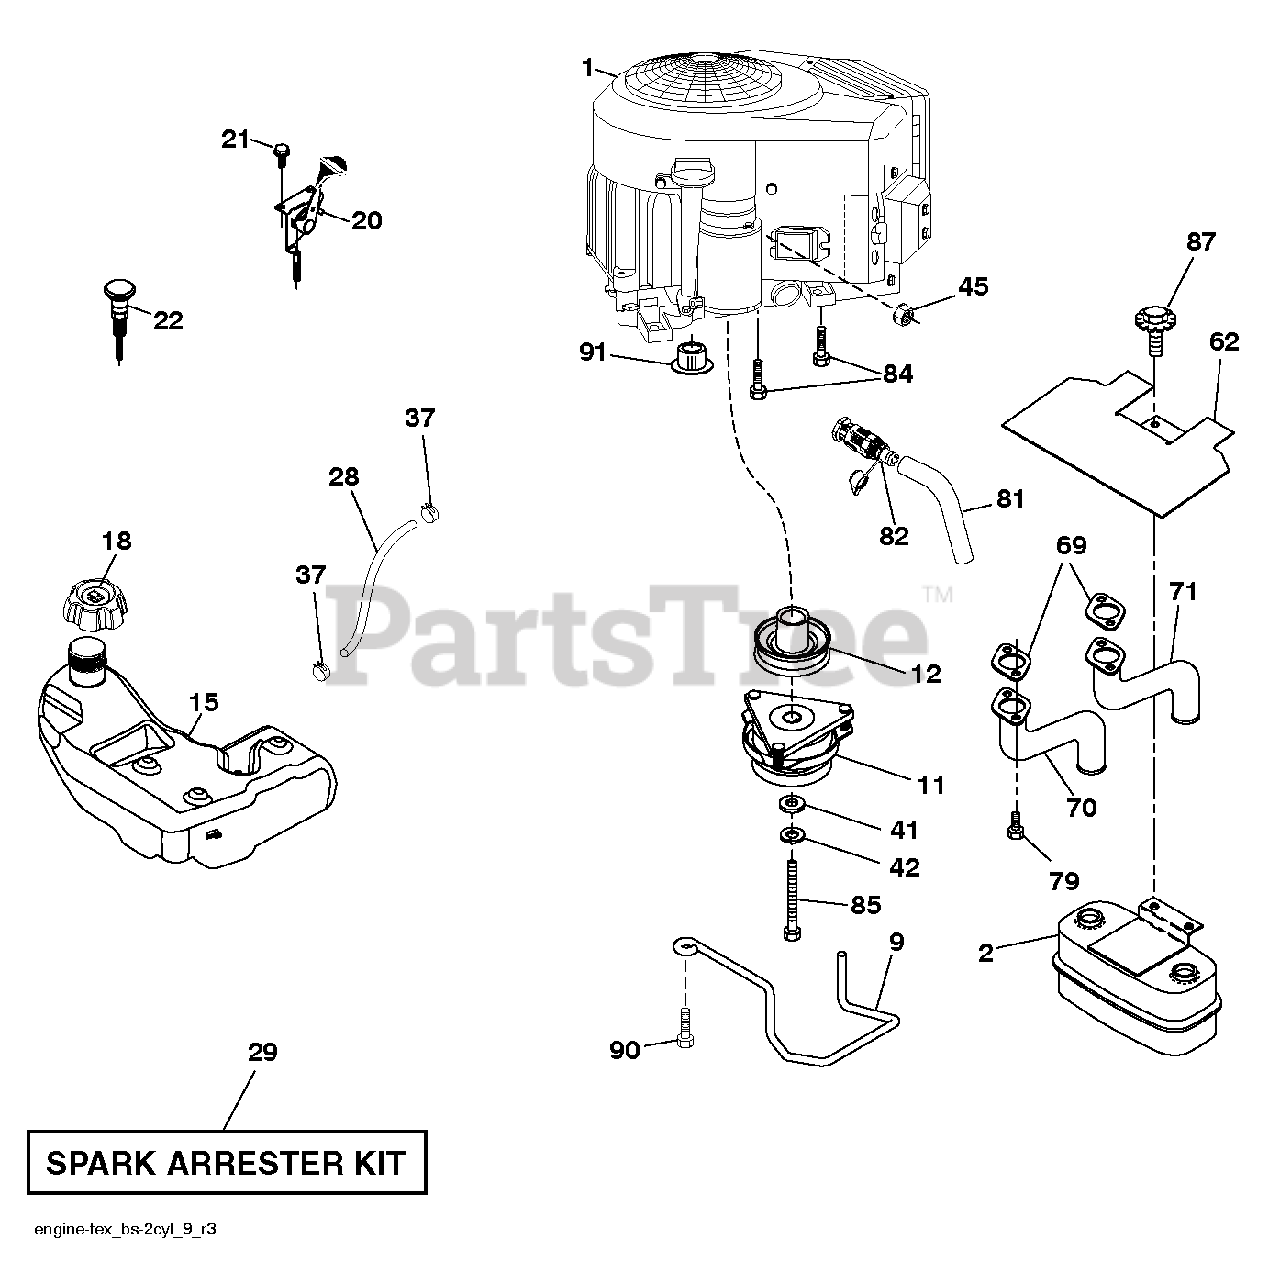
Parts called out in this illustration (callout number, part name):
2	MUFFLER.TWIN.CYL.LOW.TONE
9	KEEPER.BELT.ENGINE.4.2
11	CLUTCH.ELECTRIC.LT.48"*
12	PULLEY.ENGINE.TUFFTORQ
15	TANK.ASSY.3.GAL.EPA
18	CAP.ASM.FL.RITCH.3"E10.SYM.498
20	THROTTLE CABLE
21	SCREW.#10 X 0.750.BOS
22	CONTROL.CHOKE.ERGO.PUSH-IN.BLA
28	REPL BY 532 00 85-43
29	KIT.SPARK ARRESTOR 794945 B&S
37	HOSE CLAMP
42	LOCKWASHER
45	NUT
62	SHIELD.HEAT.MUFFLER
69	GASKET.MUFFLER
70	RP.EXHAUST.TUBE.LH.BS/TWIN
71	EXHAUST.TUBE.RH.BS/TWIN
79	SCREW.SOCKET.HEAD.5/16-18
81	TUBE, DRAIN OIL ASM.
82	VALUE.OIL.DRAIN
84	SCREW.3/8-16
85	BOLT HEX 7/16-20X4-1/4"
87	BOLT, 5/16-18 X 1 3/4
90	SCREW 3/8-16X1
91	BUSHING.1.375OD
